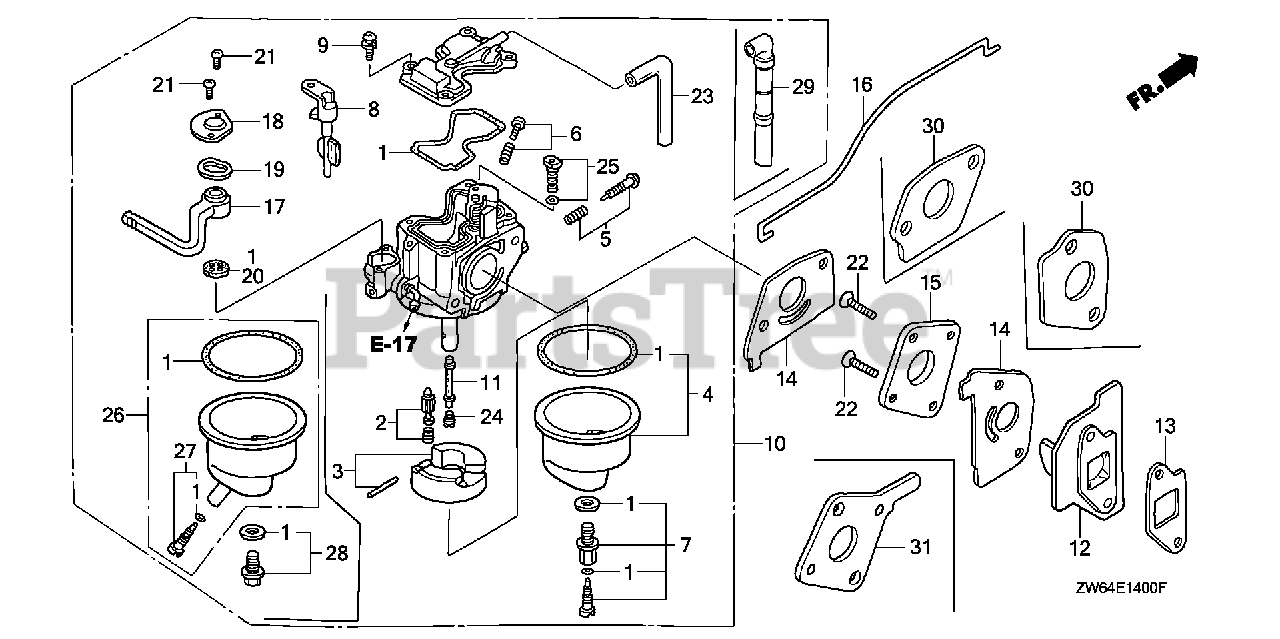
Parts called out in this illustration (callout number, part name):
1	GASKET SET (CARBURETOR NO.)
2	VALVE SET, FLOAT (SEAT NOT INCLUDED)
5	SCREW SET (CARBURETOR NO.)
6	SCREW SET (CARBURETOR NO.)
8	LEVER SET, CHOKE
9	SCREW, PAN
10	CARBURETOR ASSY. (BF33B E)
10	CARBURETOR ASSY. (BF33G A)
11	NOZZLE, MAIN (CARBURETOR NO.)
12	INSULATOR, CARBURETOR
13	GASKET, INSULATOR
14	GASKET, CARBURETOR
15	PLATE, CARBURETOR JOINT
16	ROD, CHOKE
17	LEVER, PETCOCK
18	PLATE, LEVER SETTING (CARBURETOR NO.)
19	SPRING, PETCOCK LEVER
20	GASKET, PETCOCK
21	SCREW, PAN (3X6) (CARBURETOR NO.)
22	SCREW, FLAT (5X20)
24	JET, MAIN (#60)
24	JET, MAIN (#62) (CARBURETOR NO.)
24	JET, MAIN (#65) (CARBURETOR NO.)
24	JET, MAIN (#58) (CARBURETOR NO.)
25	JET SET, PILOT (#35)
26	CHAMBER SET, FLOAT (CARBURETOR NO.)
27	SCREW SET, DRAIN (CARBURETOR NO.)
28	SCREW SET (CARBURETOR NO.)
29	TUBE ASSY., AIR VENT
30	GASKET, CARBURETOR
31	PLATE, CARBURETOR JOINT
